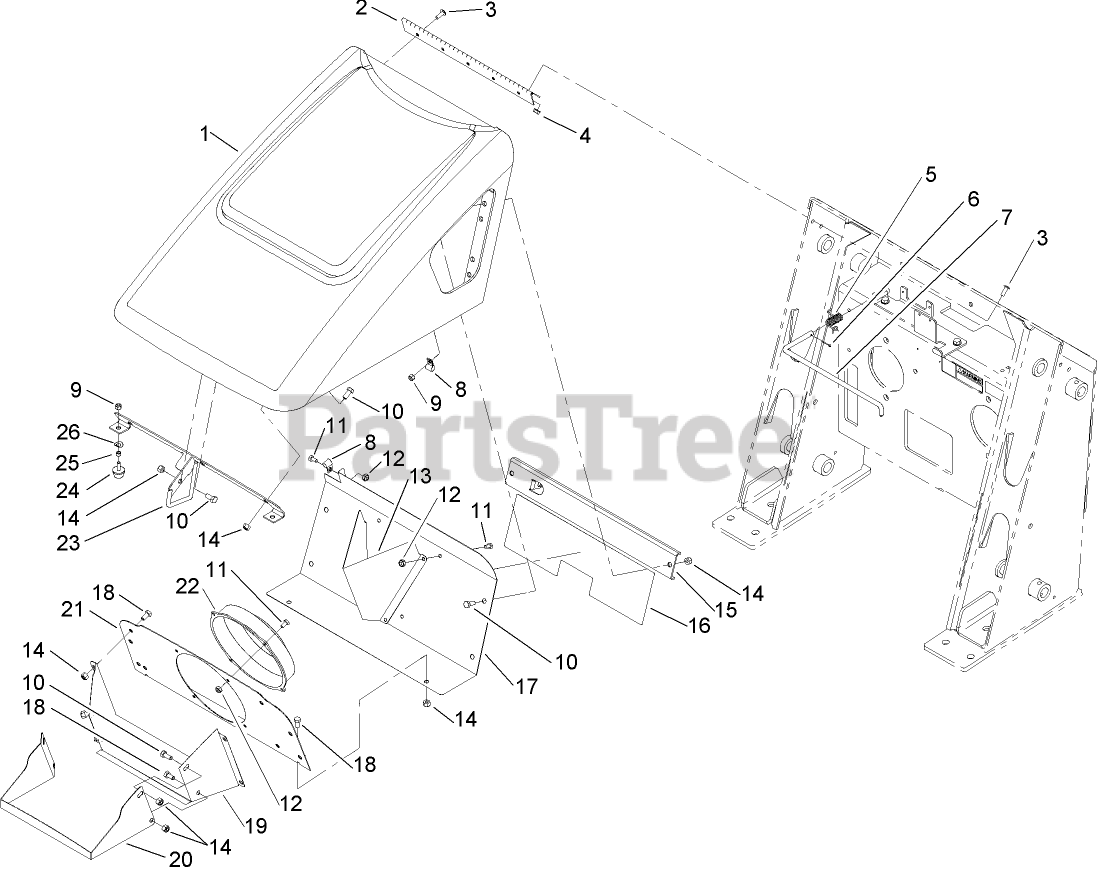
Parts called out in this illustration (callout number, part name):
1	Engine Hood ASM
2	HINGE-HOOD
3	SCREW-HEAD, TRUSS
4	NUT-HF
5	Spring-Torsion
6	PIN-COTTER
7	Rod-Support, Hood
8	CLAMP
9	NUT-LOCK, NI
10	SCREW-HH
11	SCREW-HH
12	NUT-LOCK, NI
13	BAFFLE-FAN
14	NUT-LOCK, NI
15	Bracket-Support, Hood
16	DECAL-SERVICE
17	Bracket-Fan, Back
18	SCREW-HH
19	Shroud-Fan
20	SHROUD-FAN, FRONT
21	Bracket-Baffle, Fan
23	ROD LATCH ASM
24	BUMPER
25	SPACER
26	WASHER-SPRING
